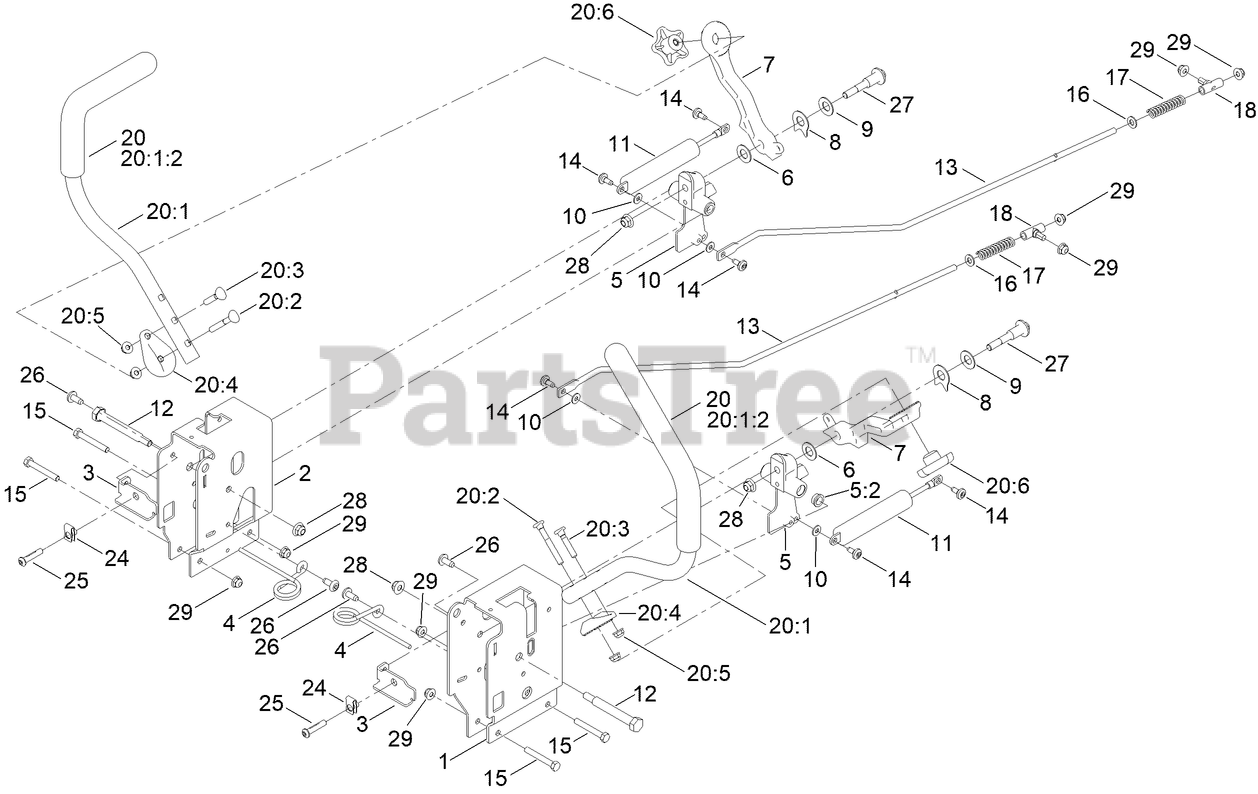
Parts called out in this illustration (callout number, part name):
1	CONTROL BOX - LH G7
2	CONTROL BOX - RH G7
3	ADJUSTMENT PLATE-CONTROL BOX
4	SPRING-TORSION
5	PIVOT ARM ASM
5:2	BUSHING-FLANGE
6	WASHER-NYLON
7	ARM-CONTROL, 32 TEETH
8	SPACER, ANTI-ROTATION
9	WASHER-BELLEVILLE
10	WASHER
11	DAMPER-NON CAVITATING
12	BOLT-PIVOT
13	ROD-HYDRO
14	SCREW-SHOULDER
15	SCREW-HH
16	WASHER-PLAIN
17	SPRING-COMPRESSION
18	MOUNT-ROD, HYDRO
20	HANDLE-CONTROL, ASM
20:1	HANDLE-CONTROL,
20:2	SCREW-HANDLE
20:3	SCREW-HANDLE
20:4	DISC-ADJUSTMENT HANDLE, 32 TEETH
20:5	NUT-HF
20:6	KNOB-HANDLE
25	SCREW-HSBH
27	BOLT-PIVOT
28	NUT-HF, NI
29	NUT-HF
